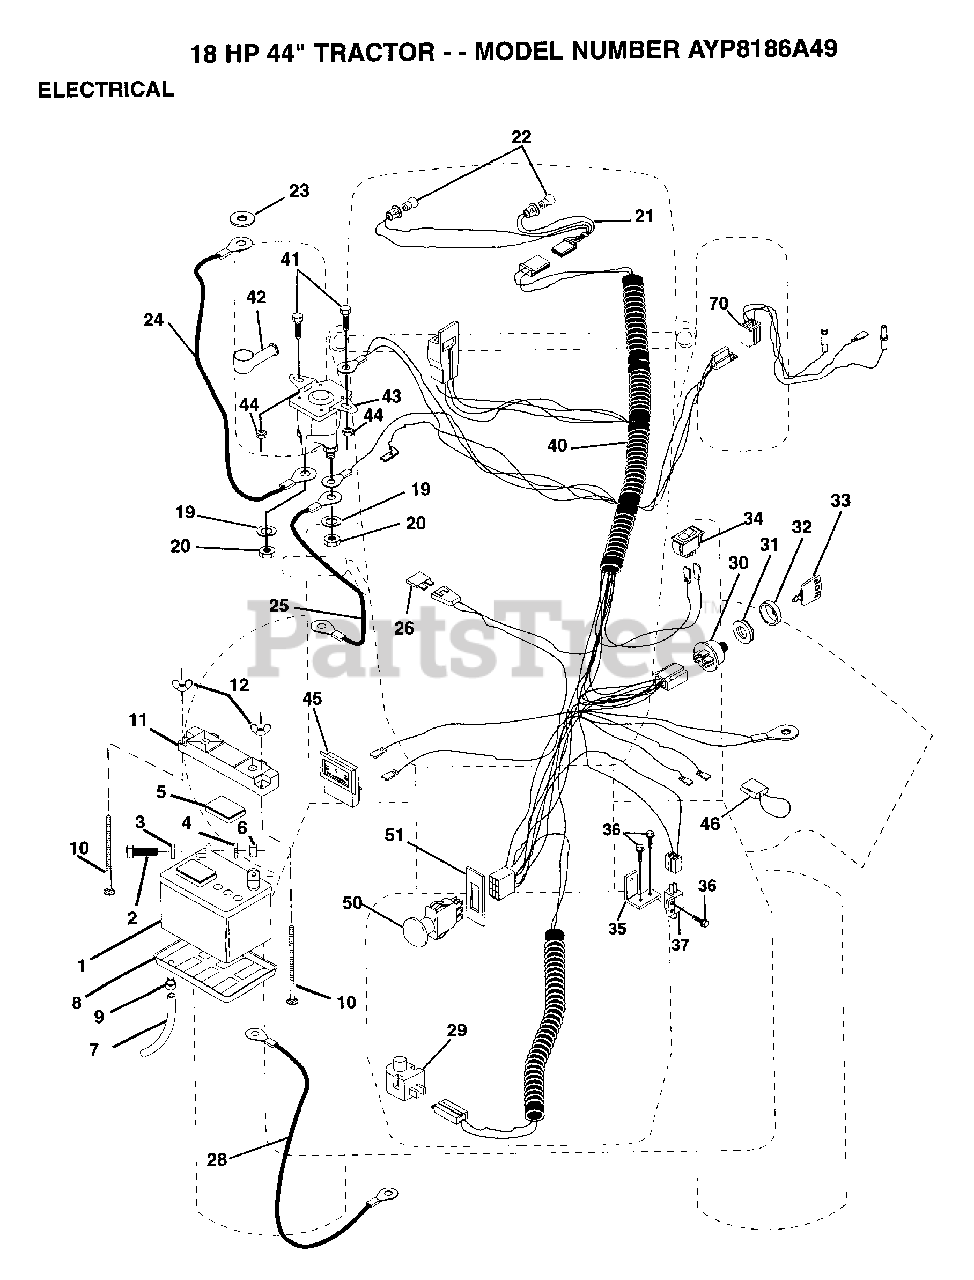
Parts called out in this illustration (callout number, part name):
2	BOLT LT
3	WASHER
4	LOCKWASHER
5	"CAP,BATTERY "
7	"DRAIN TU T, BATT"
8	"TRAY T, BATTERY"
9	HOSE CLAMP T
10	BOLT
14	WASHER.3/4X1X18GA
20	NUT
21	"HARNESS,LIGHT SOC"
22	HEADLAMP BULB
23	LOCKWASHER
24	CABLE-BATTERY T
25	CABLE-BATTERY T
26	FUSE HYT
28	CABLE T
29	SWITCH SEAT
33	KEY MLD GEN DELTA
34	SWITCH LT
35	BRACKET LT
36	SCREW
37	SWITCH-INTER. GT
40	HARNESS IGNITION
41	BOLT HXHD FIN
45	AMMETER
46	PROTECTION LOOP
51	RING RETAIN PTO
70	HARNESS ENGINE
